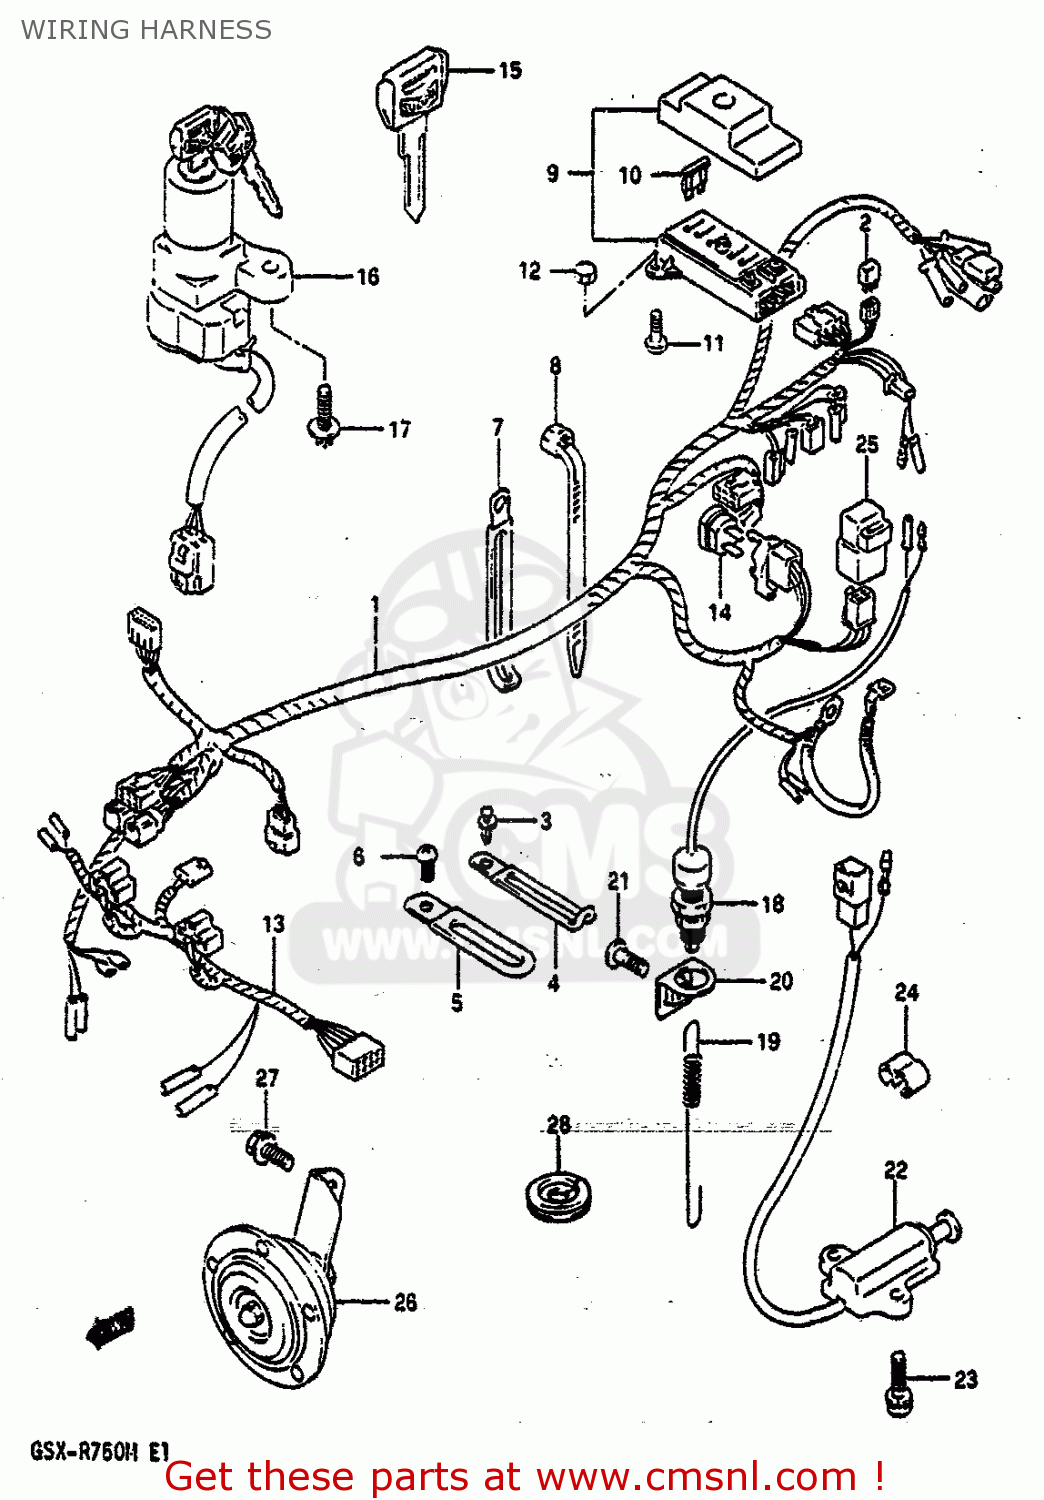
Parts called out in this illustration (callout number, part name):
1	HARNESS,WIRING
2	DIODE(STANLEY DE8804)
3	CLIP
4	CLAMP
5	CLAMP
6	SCREW
7	CLAMP
8	CLAMP(L:100)
9	BOX ASSY,FUSE
10	FUSE(10A)
11	SCREW (6X15)
12	NUT 6MM
13	WIRE,HEADLAMP LEAD
14	BREAKER ASSY,CIRCUT
15	KEY,BLANK
16	LOCK ASSEMBLY,STEERING
17	SCREW(6X18)
18	SWITCH ASSY,STOP LAMP
19	SPRING
20	BRACKET,STOP LAMP SWITCH
21	SCREW(6X12)
22	SWITCH ASSEMBLY,SIDE STAND
23	SCREW
24	CLIP
25	RELAY ASSEMBLY
26	HORN ASSEMBLY
27	BOLT
28	GROMMET
